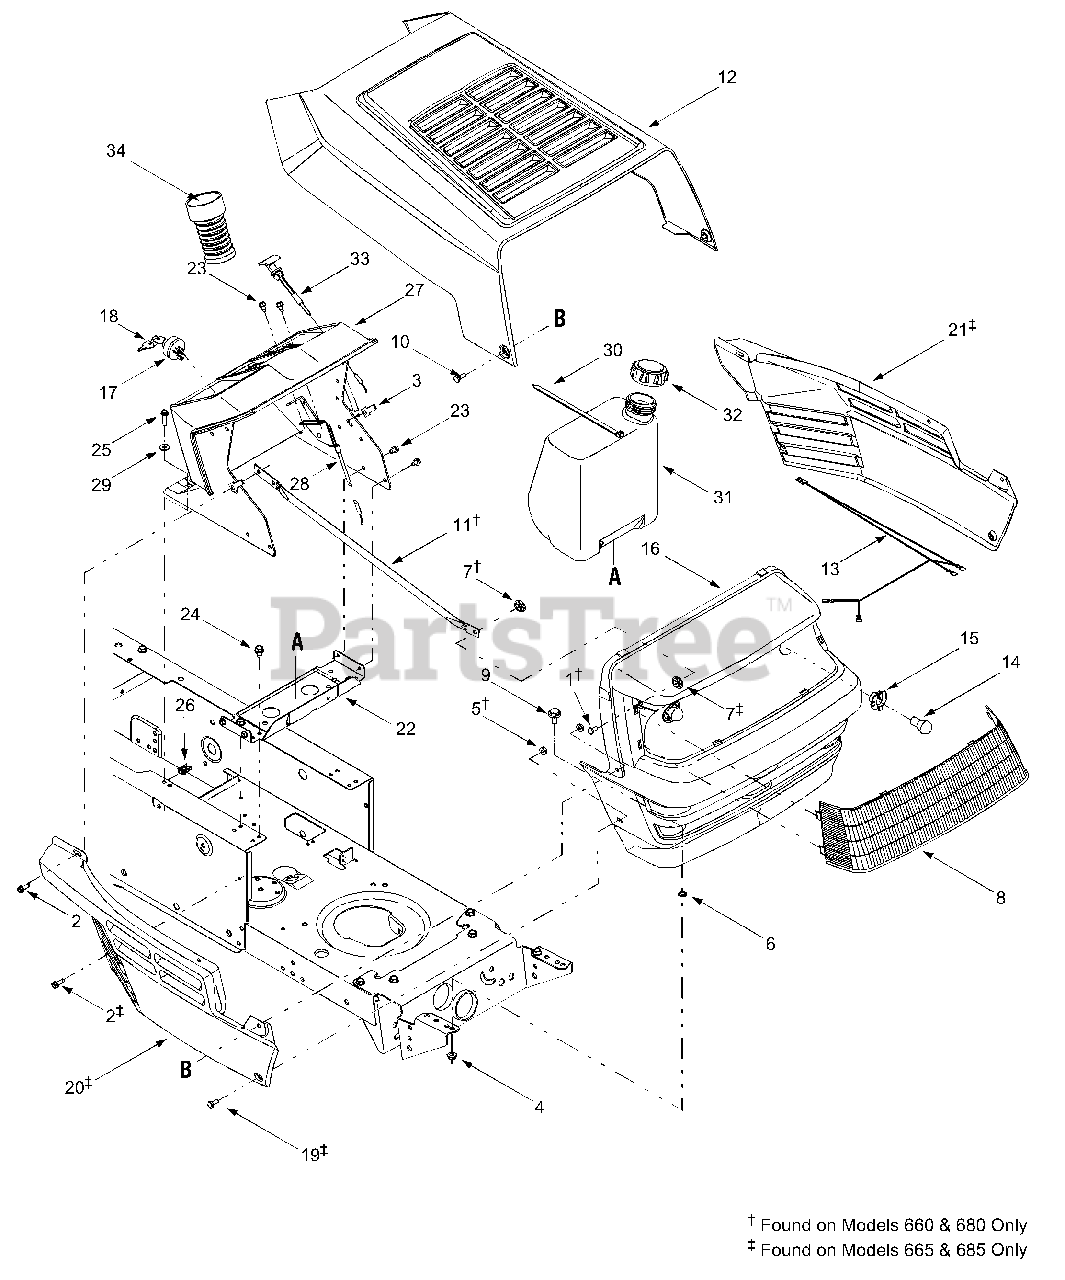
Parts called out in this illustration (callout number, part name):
1	Flat-head Rivet, 1/4
2	Self-tapping Screw, 1/4-20 x .75
3	U-type Speed Nut, 1/4-20
4	Lock Nut, 5/16-18
5	Lock Nut, 1/4-20
6	Speed Nut, .3125
7	Push-on Nut, .25
8	Lens
9	Shoulder Screw, 5/16-18 x .625
10	Shoulder Screw, 1/4-20 x .375 /.125
14	Headlamp, 12V
15	Headlamp Socket
16	Grille
17	Ignition Switch, 6-pin
18	Keys (pair)
19	Hex Screw, 1/4-20 x .620
24	Self-tapping Screw, 5/16-18 x .5
25	Self-tapping Screw, 1/4-20 x 1.0
26	U-type Speed Nut, 1/4-20
27	Dash Panel
28	Throttle / Choke Control, 18.5"
29	Flat Washer, .260 x .720 x .060
30	Cable Tie, 34.75
31	Fuel Tank, 1.5 gal.
32	Fuel Tank Cap
33	Choke Control, 38"
34	Steering Bellow, 4.75"
